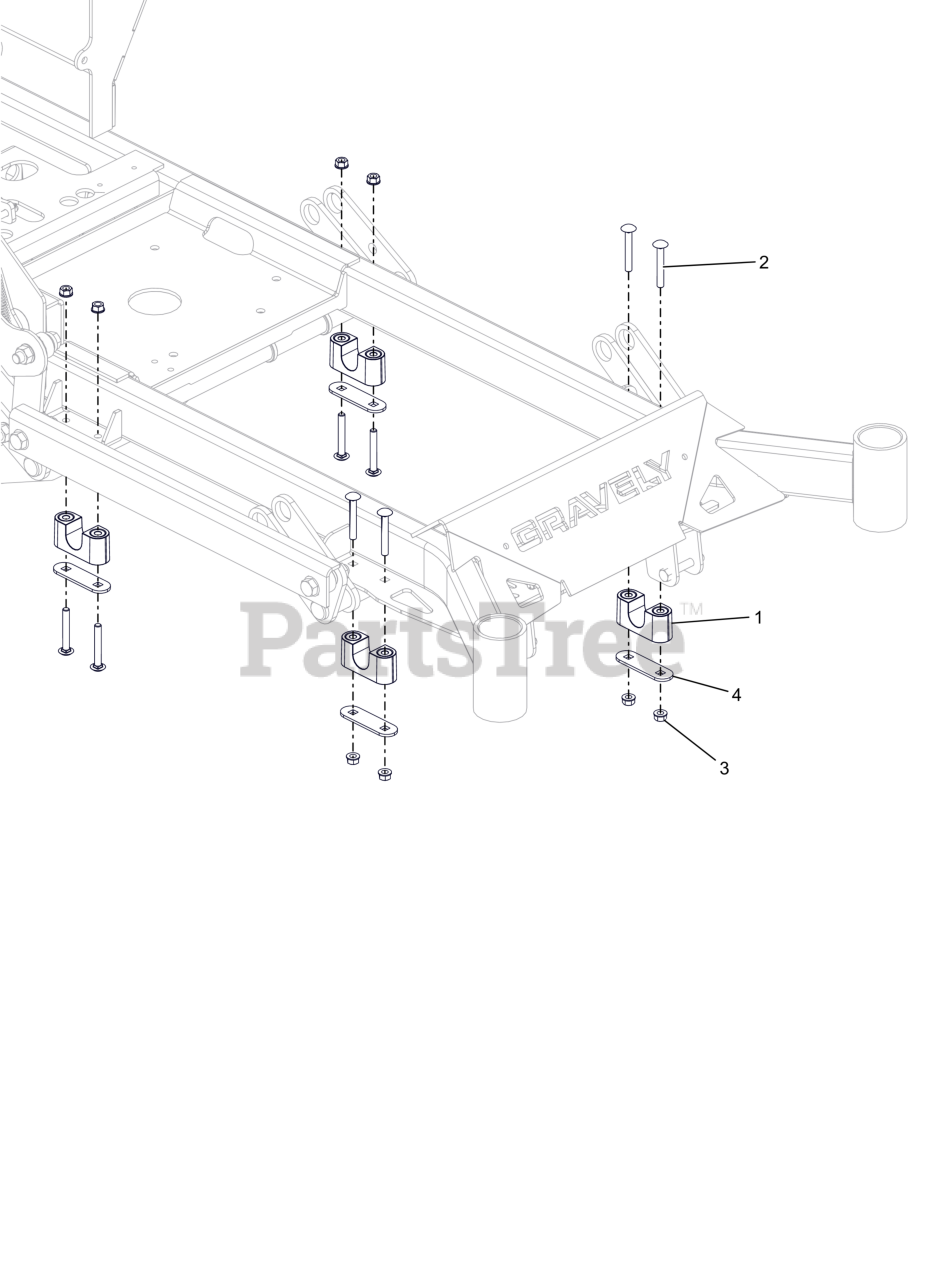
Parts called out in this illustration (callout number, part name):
1	ASM-BUSHING, DECK LIFT
2	BLT, RHSSN.31-18X2.25 G5 ZCC
3	NUT,LK-CTR-FLG .31-18 GF ZCC
4	PLATE, BEARING SUPPORT
